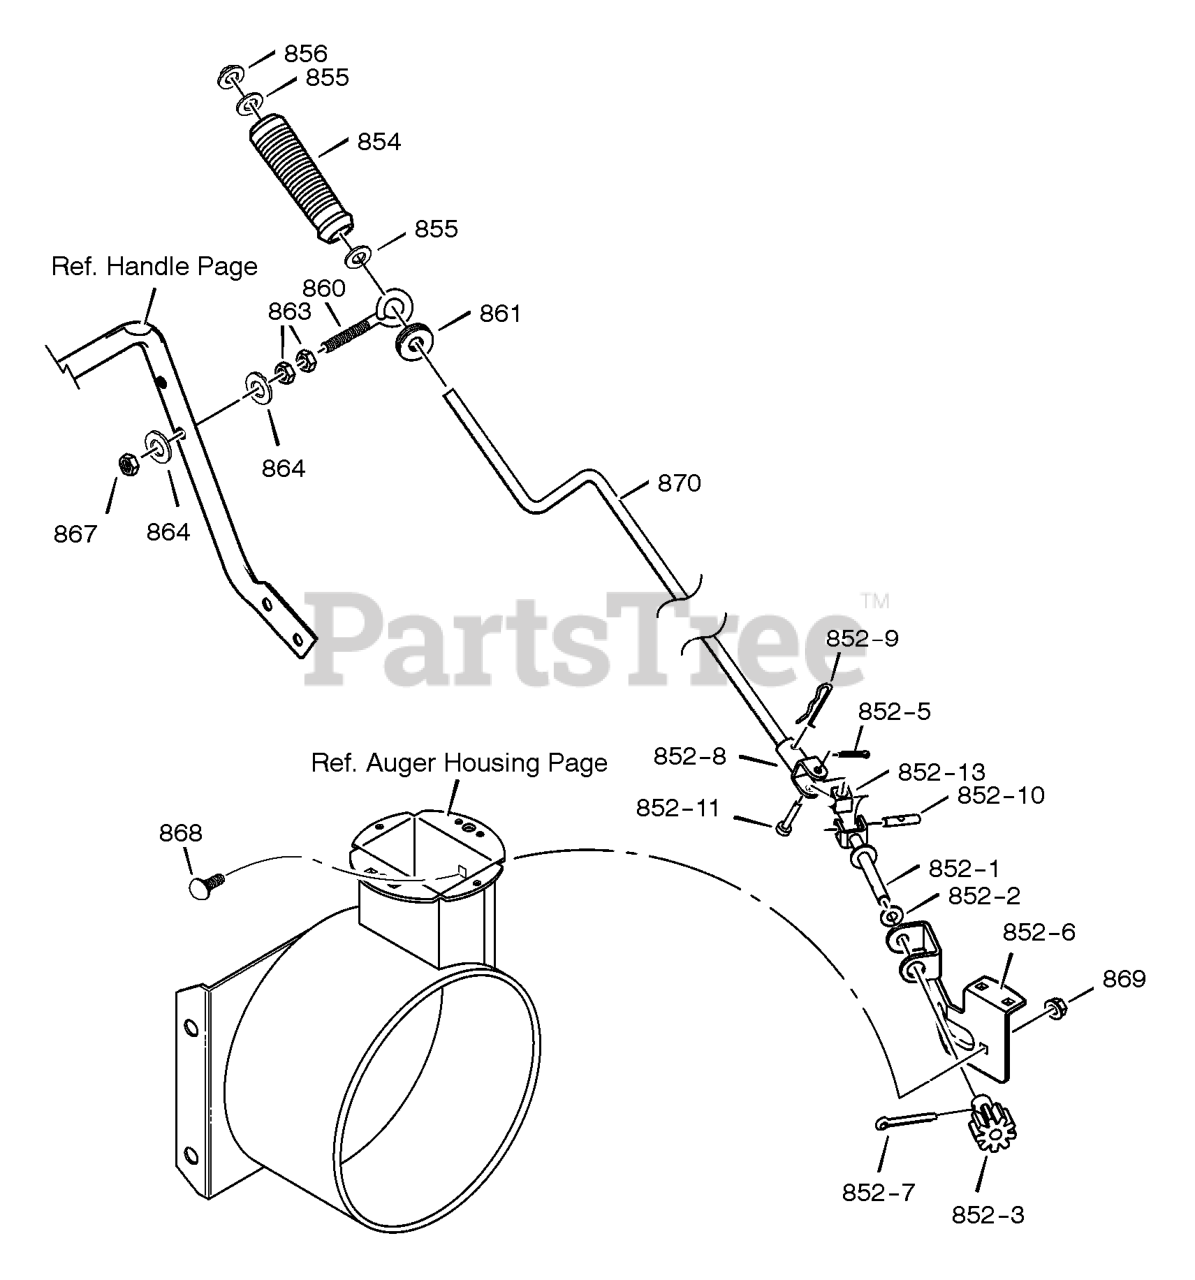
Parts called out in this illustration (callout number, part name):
852-1	ASSEMBLY, YOKE & ROD
852-2	WASHER, CURVED SPRING
852-3	GEAR, CHUTE ROTATION 9T
852-5	PIN, COTTER
852-6	BRACKET, GEAR MOUNT
852-7	PIN, COTTER
852-8	ASSEMBLY, YOKE ADAPTER YZ
852-9	PIN, HAIR
852-10	PIN, UNIVERSAL JOINT
852-11	PIN, CLEVIS
852-12	PIN, COTTER
852-13	HOUSING, UNIVERSAL
854	KNOB, SLEEVE
855	FLATWASHER
856	NUT, PUSH ON 3/8"
860	EYE BOLT 3/8-16X6.00
861	GROMMET, EYE BOLT
863	NUT, 3/8-16 HEXJAM
864	FLATWASHER .406X.81X.066
867	NUT, 3/8-16 HEXNYL
868	BOLT, CARRIAGE 1/4-20 X 1.00
869	NUT, NYLOCK 1/4-20
870	CRANK, ASSY CHUTE
